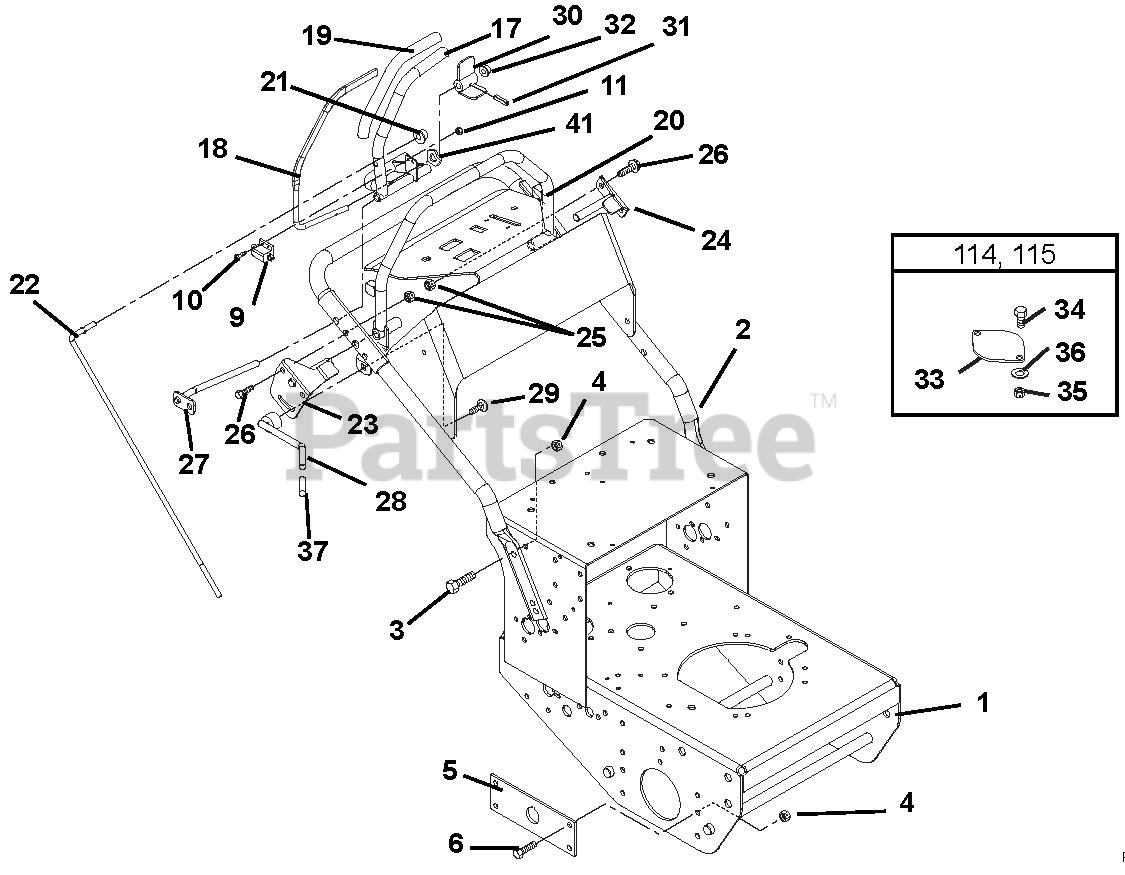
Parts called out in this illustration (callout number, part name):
1	Kit-Frame with Decals
2	Kit, Handlebar with Decals GR13/15-Pro Steer
3	Bolt-Hex .38-16 x 1.00 Grade 5
4	Nut-Locking-Nylon .38-16
5	Plate, Support
6	Bolt-Hex .38-16 x 1.00 Grade 5
9	Switch, Interlock
10	Screw-Machine 10-24 x .75 Hex Washer Head
11	Nut-Locking-Nylon 10-24 with Insert
17	Weldment, Lever-Right Hand Speed Control
17	Weldment-Lever-Left Hand Speed Control
18	Lever- Operator Presence
19	Grip- Handlebar
20	Weldment- Speed Control Stop
21	Ring-Retaining-External .375 x .010
22	Rod, Steering
23	Weldment, Control Stop Limiter-Right Hand
24	Weldment, Control Stop Limiter-Left Hand
25	Nut-Locking-Top-Flange .31-18
26	Bolt-Hex .31-18 x 1.75 Grade 5
27	Weldment, Speed Control Pivot- Right Hand
27	Weldment, Speed Control Pivot- Left Hand
28	Lever- Control Stop Lock
29	Bolt-Round Head Square Neck .38-16 x .75 Grade 2
30	Actuator, Switch
31	Pin-Roll .125 x .75
32	Nut-Push .312
33	Plate, Cover
34	Bolt-Hex .38-16 x .75 Grade 5
35	Nut-Locking-Flange .375-16
36	Washer-Flat-Steel .406 x .812 x .065
37	Grip, Hand Clutch Lever
41	Washer, Wave
